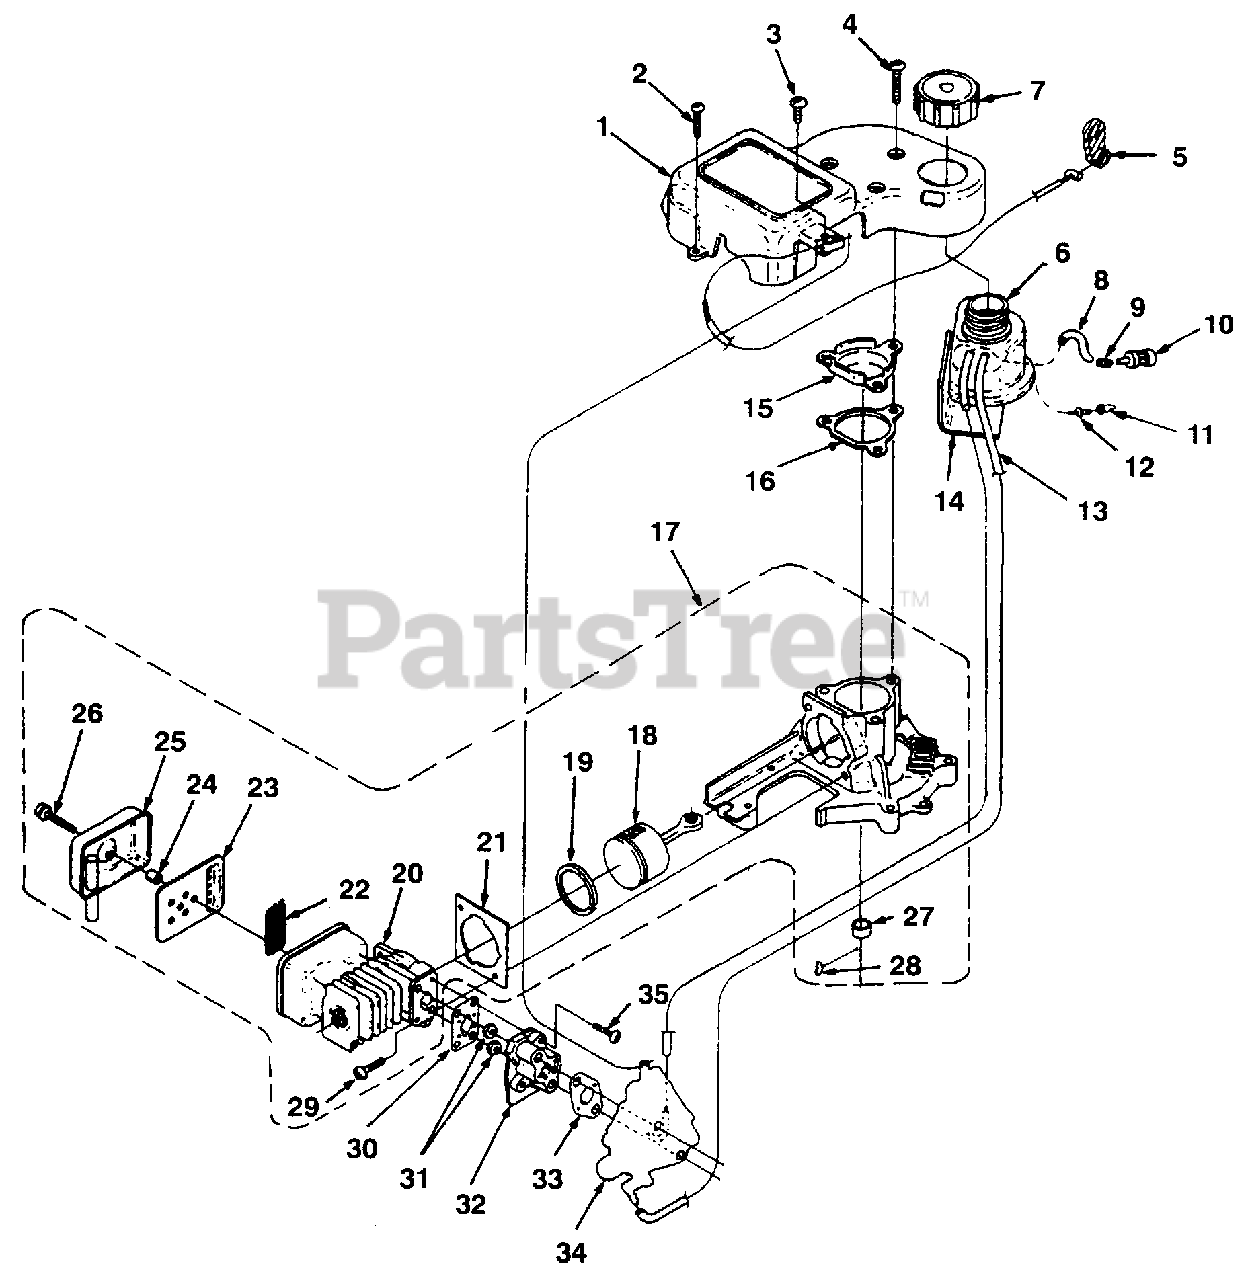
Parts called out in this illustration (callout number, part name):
1	COVER-Engine
2	SCREW-Thread Form. (#8 X 3/4")
3	SCREW-Thread Form. (#10 X 1/2")
4	SCREW-Thread Form. (10-24 X 3/4")
5	LEVER-Trigger
6	FUEL TANK ASSEMBLY
7	CAP-Fuel
8	TUBING-Rubber (5 1/2")
9	CLAMP-Wire
10	FILTER-Fuel
11	VALVE- Filter
12	FITTING
13	TUBING-Rubber (6 1/4")
14	SPACER-Fuel Tank
15	COVER-Crankcase
16	GASKET-Crankcase
17	SHORT BLOCK
18	PISTON & ROD
19	RING-Piston
20	CYLINDER & MUFFLER ASSEMBLY
21	GASKET-Cylinder
22	SCREEN-Spark Arrestor
23	BAFFLE-Muffler
24	SPACER-Muffler
25	COVER-Muffler
26	SCREW-Thread Form. (8-32 X 1")
27	SPACER
28	KEY-Woodruff
29	SCREW-Machine (10-24 X 3/4")
30	GASKET-Heat Dam
31	NUT-Hex (10-24)
32	HEAT DAM
33	GASKET-Carburetor
34	CARBURETOR (Walbro)
35	SCREW-Thread Form. (10-24 X 1")
